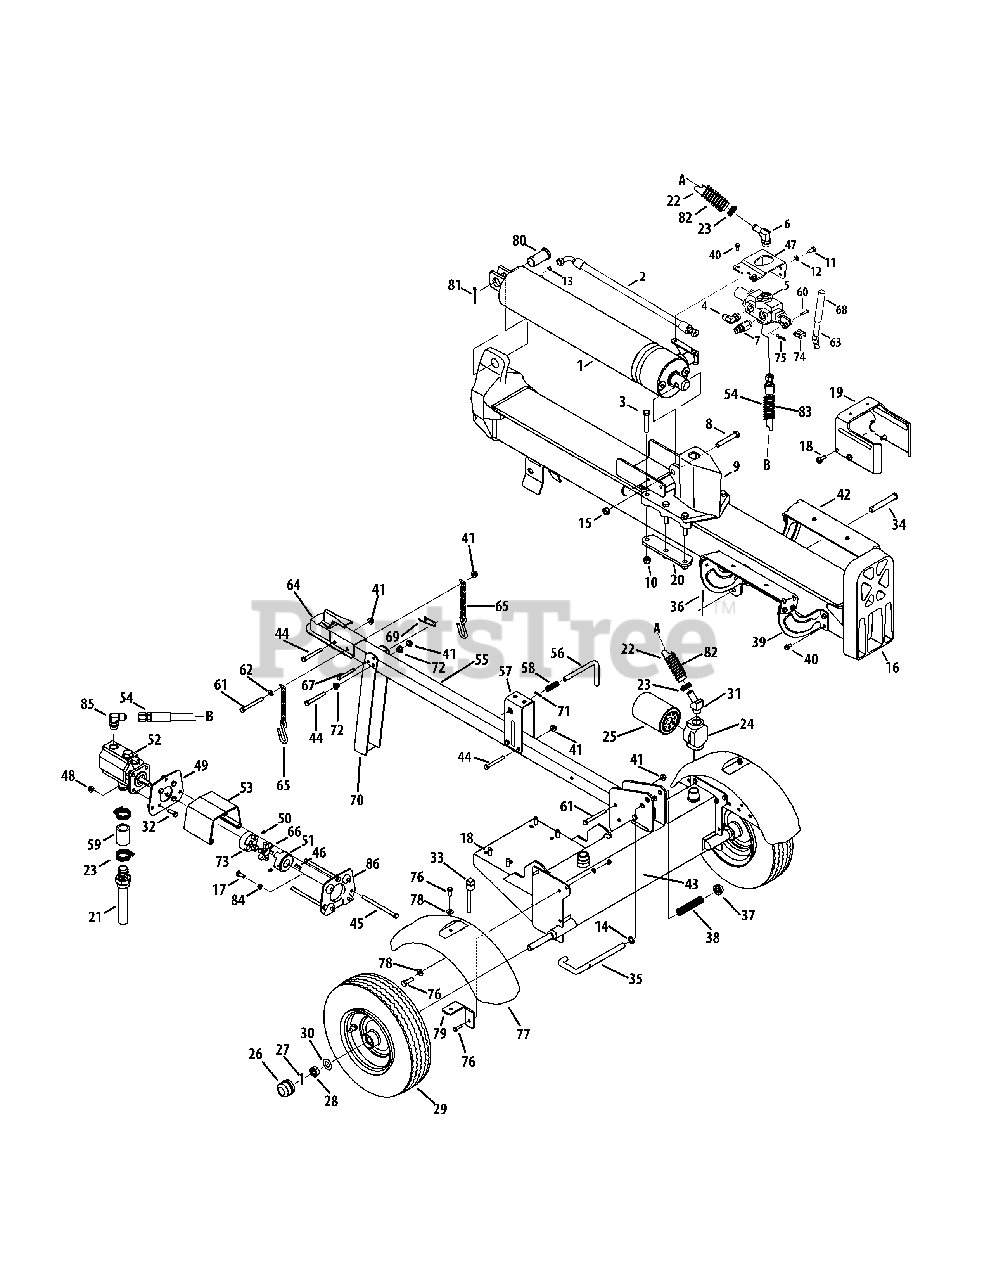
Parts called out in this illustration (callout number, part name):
1	Hydraulic Cylinder
2	Hydraulic Tube
3	Hex Cap Screw, 1/2-20 x 2.75
4	90 Degree Solid Adapter
5	Control Valve
6	Return Elbow
7	Nipple Pipe, 1/2-14
8	Hex Cap Screw, 1/2-13 x 3.25
9	Wedge Assembly
10	Hex Lock Nut, 1/2-20
11	Hex Cap Screw, 3/8-16 x .75
12	Lock Washer, 3/8
13	O-Ring, .489 ID x .070 Dia.
14	Flat Washer, .635 x.93 x.06
15	Hex Lock Nut, 1/2-13
16	Beam Assembly
17	Hex Cap Screw, 5/16-24 x .75
18	Self Tapping Screw, 3/8-16 x 1.0
19	Dislodger Bracket
21	Inlet Filter
22	Return Hose, 3/4 x 44
23	Hose Clamp, 5/8
24	Filter Housing
25	Oil Filter
27	Cotter Pin
28	Slotted Nut, 3/4-16
29	Complete Wheel Assembly
29	Dust Seal
29	Roller Bearing
30	Flat Washer, .760 x.500
31	Hydraulic Fitting, 1 1/16 Orb x .75
32	Hex Screw, 5/16-18 x 1.00
33	Vented Dipstick
34	Clevis Pin
36	Cotter Pin
38	Compression Spring
39	Log Tray Bracket
40	Hex Washer Screw, 5/16-18 x .750
41	Flange Lock Nut, 3/8-16
45	Hex Screw, 5/16-18 x 4.00
46	Square Key, 3/16" x .75
47	Outer Valve Bracket
48	Flange Lock Nut, 5/16-18
49	Rear Coupling Support Bracket
50	Set Screws
51	Coupling, .750
53	Coupling Shield
54	High Pressure Hydraulic Hose
55	Tongue Assembly
56	Latch Rod
58	Compression Spring
60	Clevis Pin
61	Hex Cap Screw, 3/8-16 x 3.50
62	Flat Washer, .375 x.738 x.063
63	Hydraulic Valve Control
64	Hitch Coupling Assembly
66	Spider Bushing
67	Clevis Pin
69	Spring Pin
71	Spiral Pin
72	Plastic Bushing, .380 ID
73	Coupling, .500
74	Valve Handle Link
75	Cotter Pin, Bow Tie
76	Self-Tapping Screw, 5/16-18 x 1.00
78	Flat Washer
79	Fender Mounting Bracket
80	Clevis Pin, 1.25 x 2.50
81	Cotter Pin, 3/16 x 2
82	Hose Guard, 48"
83	Hose Guard, 44"
84	Lock Washer, 5/16
85	45 Degree Elbow Fitting
86	Front Coupling Support Bracket
